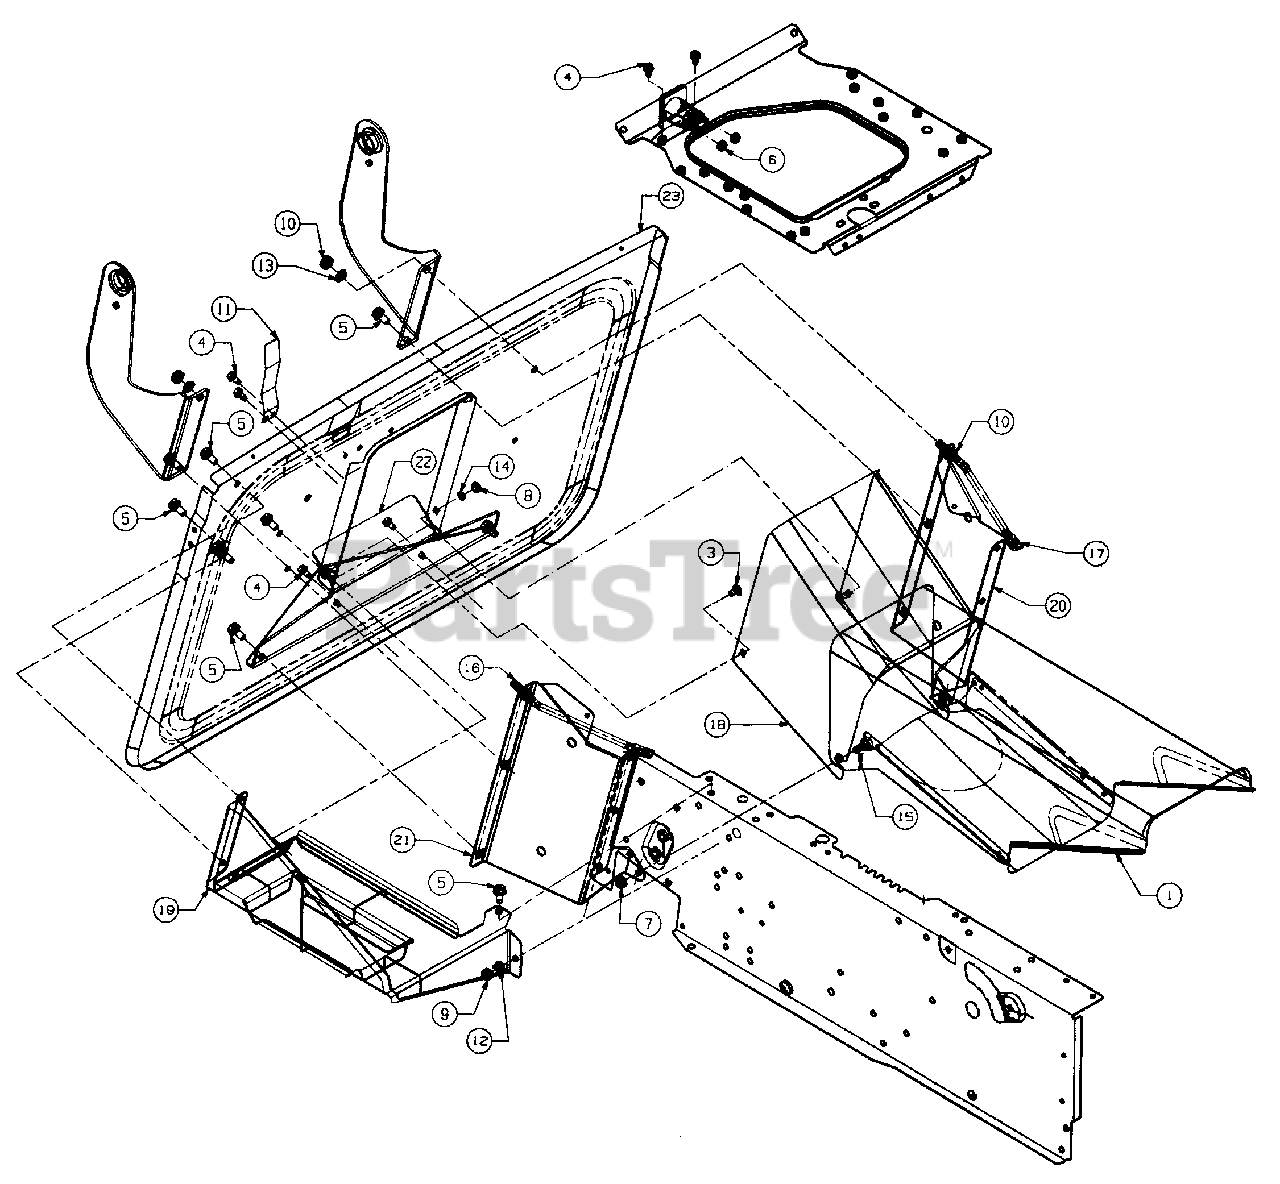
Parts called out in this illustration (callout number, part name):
1	Chute Ass'y. Center Section
3	Carr. Bolt 1/4-20 x .5" Lg.
4	Hex Wash. Hd. TT-Tap Scr. 1/4-20 x .5" Lg.
5	Hex Wash. Hd. SF-Tap Scr. 5/16 x .5" Lg.
6	Hex Sems Nut 1/4-20 Thd.
7	Hex Sems Nut 5/16-18 Thd.
8	Hex Nut 1/4-20 Thd. (Gr. 5)
9	Hex Nut 5/16-18 Thd. (Gr. 5)
10	Hex Nut 3/8-16 Thd. (Gr. 5)
11	Spring Switch
12	L-Wash. 5/16" I.D.
13	L-Wash. 3/8" I.D.
14	L-Wash. 1/4" I.D.
15	Shld. Bolt .437" x .56" Lg.
16	Brace Rod-R.H.
17	Brace Rod-L.H.
18	Chute Cover Brkt.
19	Battery Tray
22	Hitch Plate
23	Grass Catcher Support
